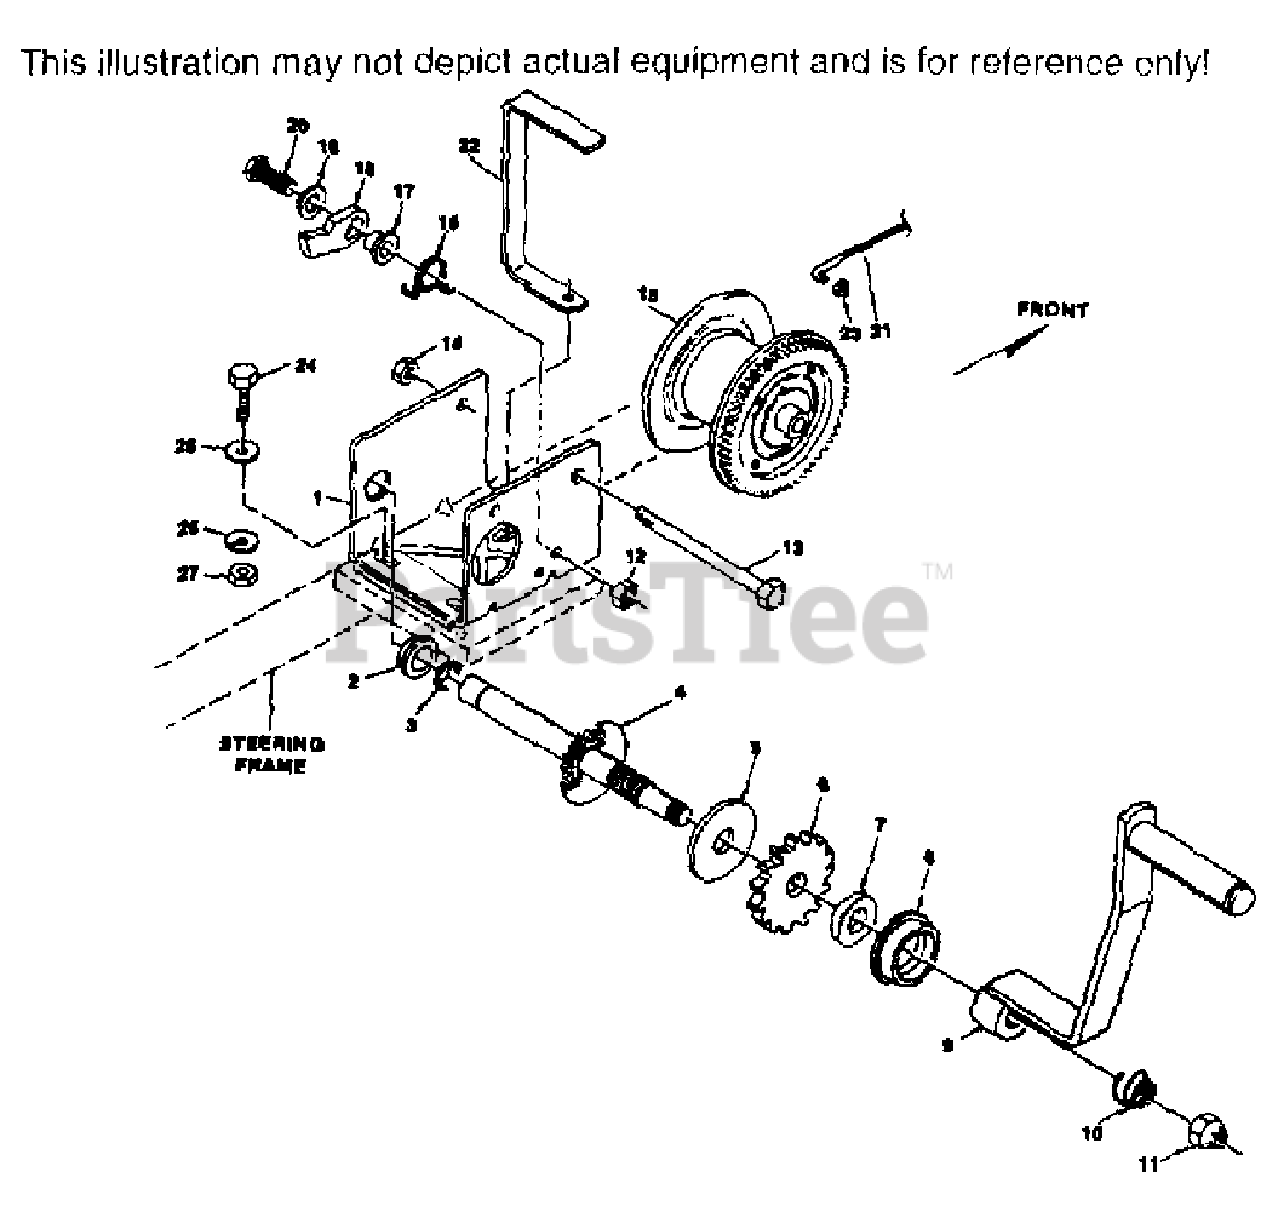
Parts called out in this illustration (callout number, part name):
1	WINCH ASSEMBLY(INCL. 1-8, 10-20)
2	SHAFT BUSHING
3	E-RING
4	DRIVE SHAFT
6	RATCHET WHEEL
7	PRESSURE WASHER
8	SHAFT BUSHING
9	WINCH HANDLE
10	HANDLE SPRING
11	HANDLE NUT
12	HEX LOCKNUT, 3/8-16
13	REEL SHAFT
14	LOCK NUT, 7/16-14
15	WINCH REEL
16	RATCHET SPRING
17	RATCHET SPACER
18	RATCHET PAWL
19	FLAT WASHER
20	RATCHET BOLT
21	WINCH CABLE ASSEMBLY
22	CABLE GUIDE
23	HEX LOCK NUT, 1/4-28
